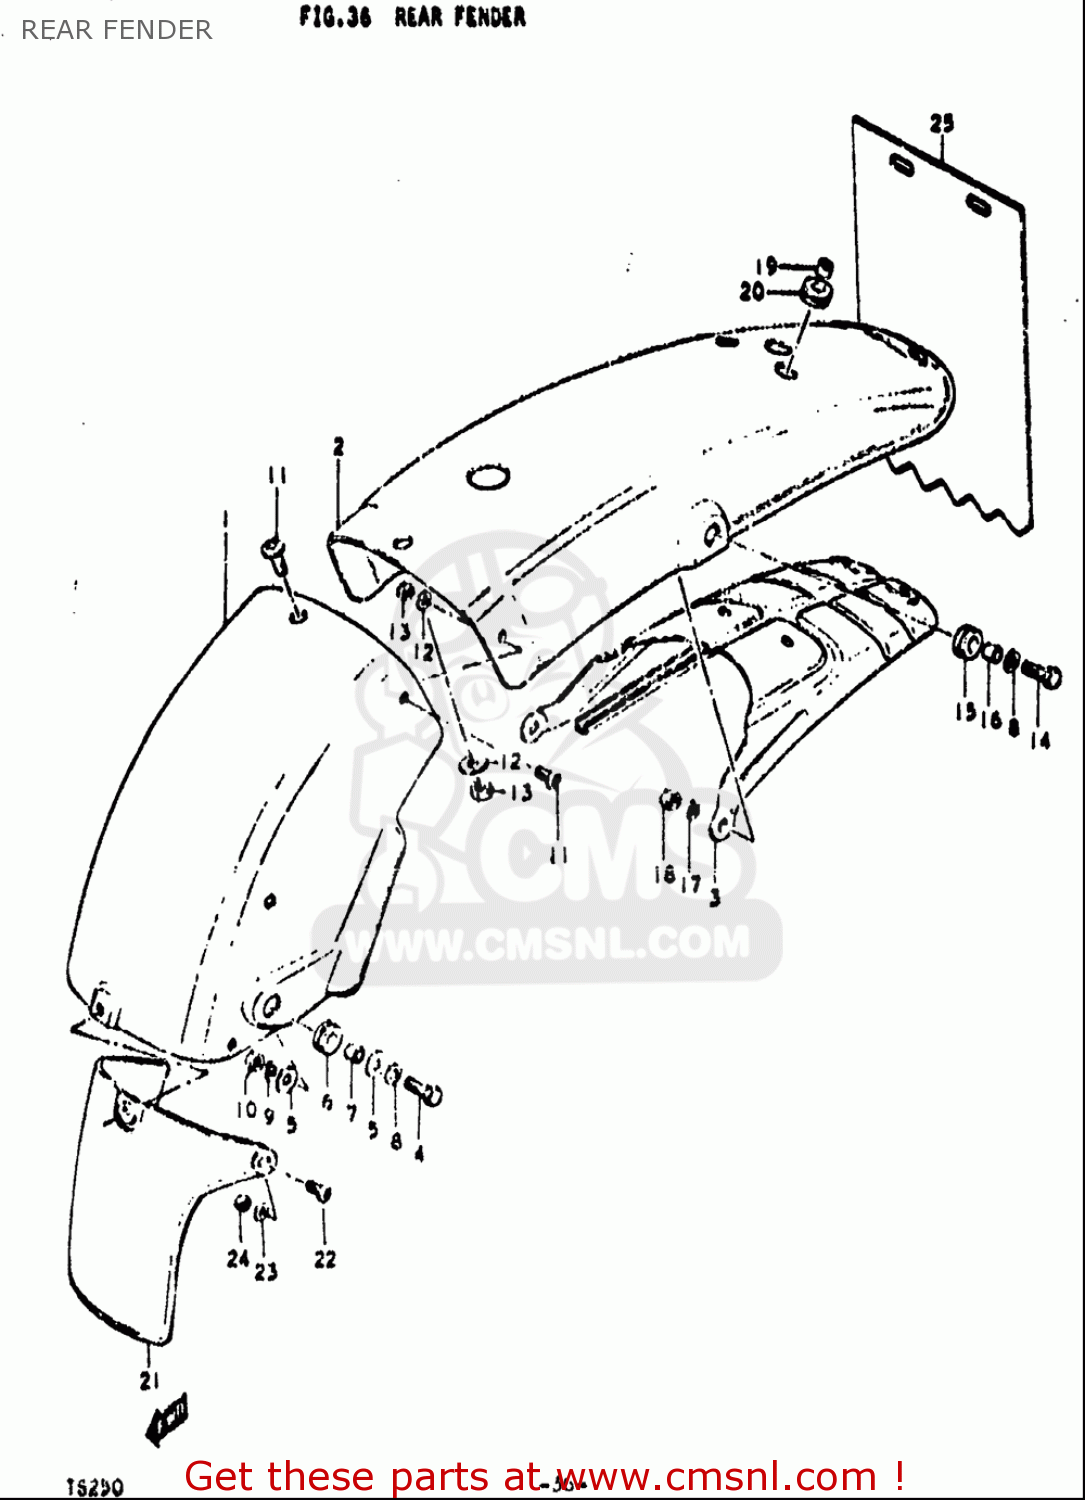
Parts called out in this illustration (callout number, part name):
4	BOLT
5	WASHER(6.5X20X1.2)
6	CUSHION
7	SPACER(6.1X9X7.5)
8	WASHER
9	WASHER,LOCK
10	NUT
11	SCREW
12	WASHER
13	NUT
14	BOLT
15	CUSHION
16	SPACER(6.1X9X7.5)
17	WASHER,LOCK
18	NUT
19	SPACER(6.1X9X7.5)
20	CUSHION
22	SCREW
23	WASHER
24	NUT
